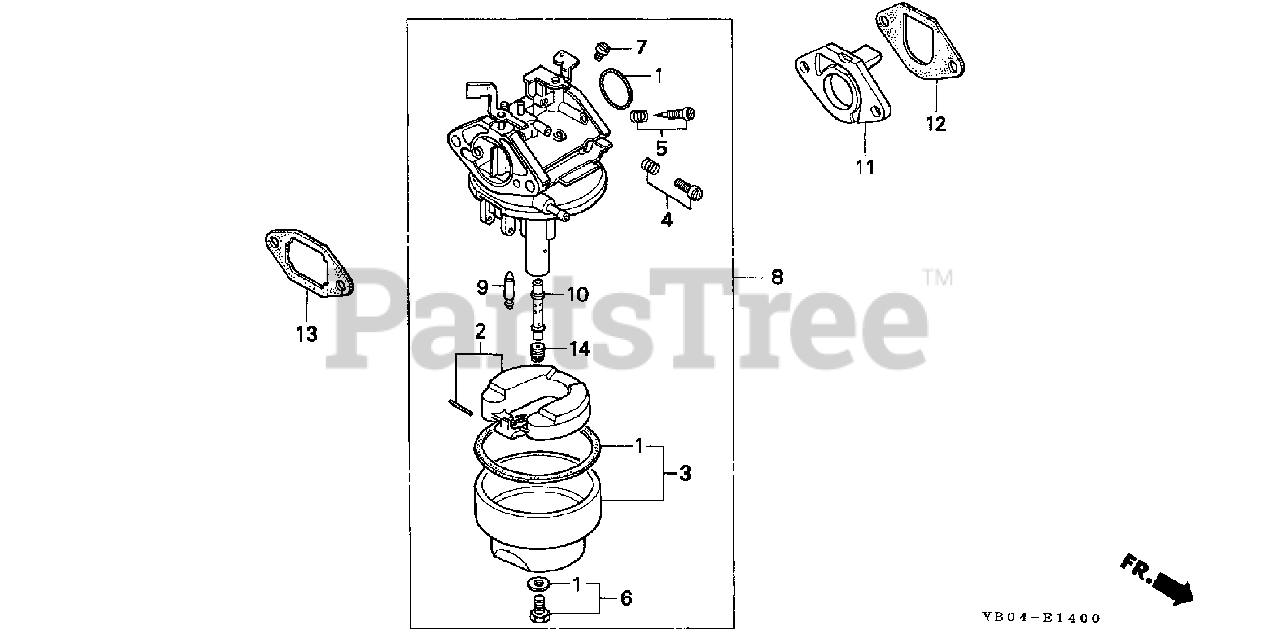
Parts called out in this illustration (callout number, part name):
1	GASKET SET
3	CHAMBER SET, FLOAT
4	SCREW SET A
5	SCREW SET A
6	SCREW SET B
7	SCREW, PLUG
8	CARBURETOR ASSY. (NOT AVAILABLE)
9	VALVE, FLOAT
10	NOZZLE, MAIN (NOT AVAILABLE)
11	INSULATOR, CARBURETOR
12	GASKET, INSULATOR
13	GASKET, AIR CLEANER
14	JET, MAIN (#50)
14	JET, MAIN (#52)
14	JET, MAIN (#55)
